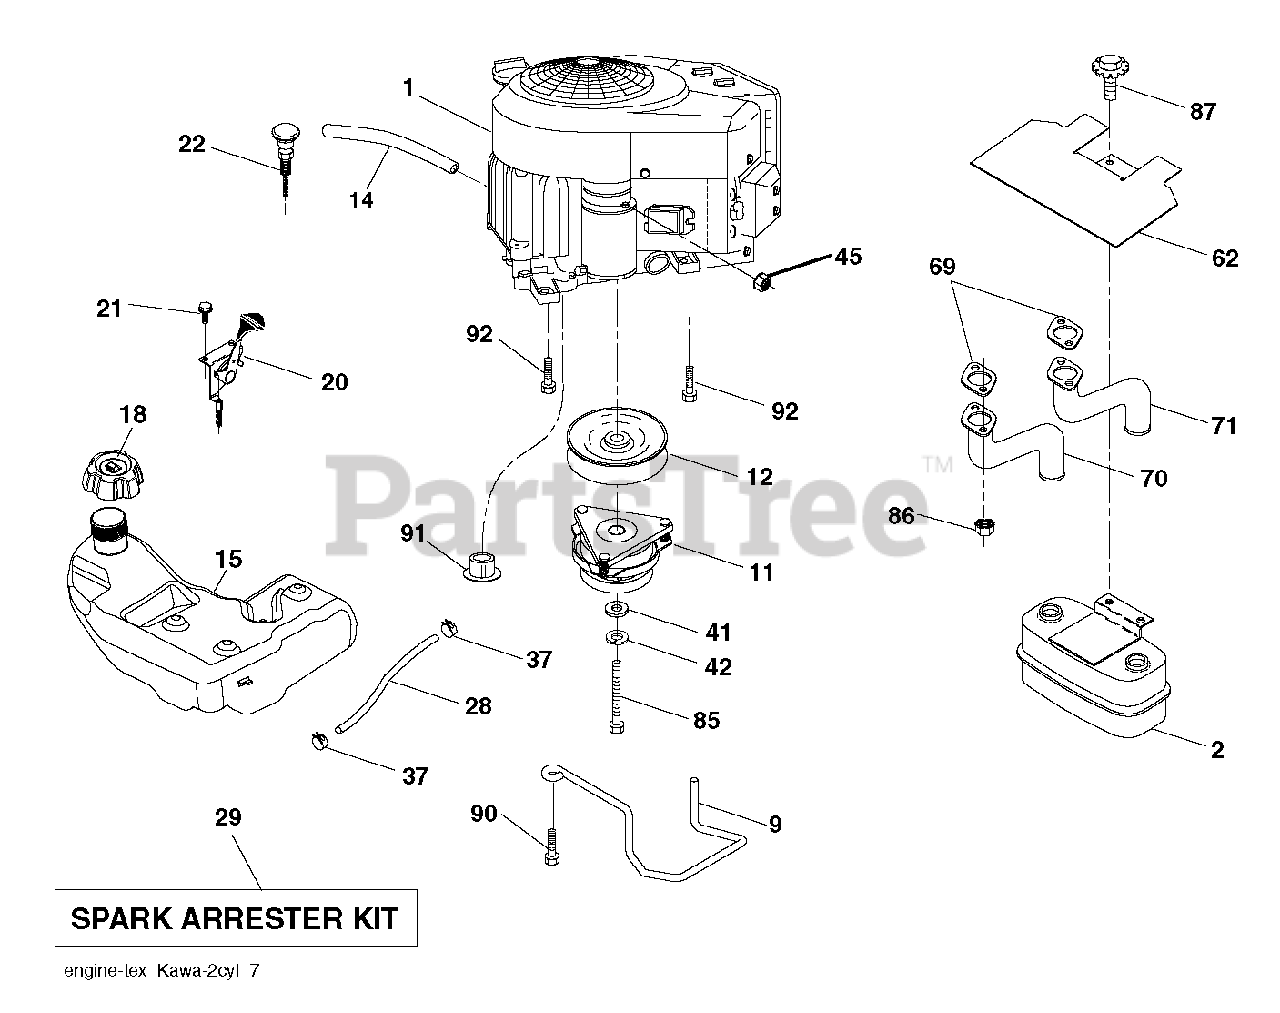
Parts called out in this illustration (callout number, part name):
2	MUFFLER.TWIN.CYL.LOW.TONE
9	KEEPER.BELT.ENGINE.4.2
11	CLUTCH.ELECTRIC.LT.48"*
12	PULLEY.ENGINE.TUFFTORQ
14	TUBE, DRAIN OIL ASM.
15	TANK.FUEL.4GAL
18	CAP.FL.R.3'N/CARB.H.CROWN.498
20	THROTTLE CABLE
21	SCREW.#10 X 0.750.BOS
22	CONTROL.CHOKE.ERGO.PUSH-IN.BLA
28	REPL BY 532 00 85-43
29	KIT.SPARK ARRESTOR 794945 B&S
37	HOSE CLAMP
42	LOCKWASHER
45	NUT
62	SHIELD.HEAT.MUFFLER
70	TUBE.EXHAUST.LH.FR961/FR730
71	TUBE.EXHAUST.RH.FR961/FR730
85	BOLT HEX 7/16-20X4-1/4"
86	NUT.HEX.FLANGE.TOPLOCK
87	Bolt, 5/16-18 X 1-3/4
90	SCREW 3/8-16X1
91	BUSHING.1.375OD
92	SCREW 3/8-16X1
